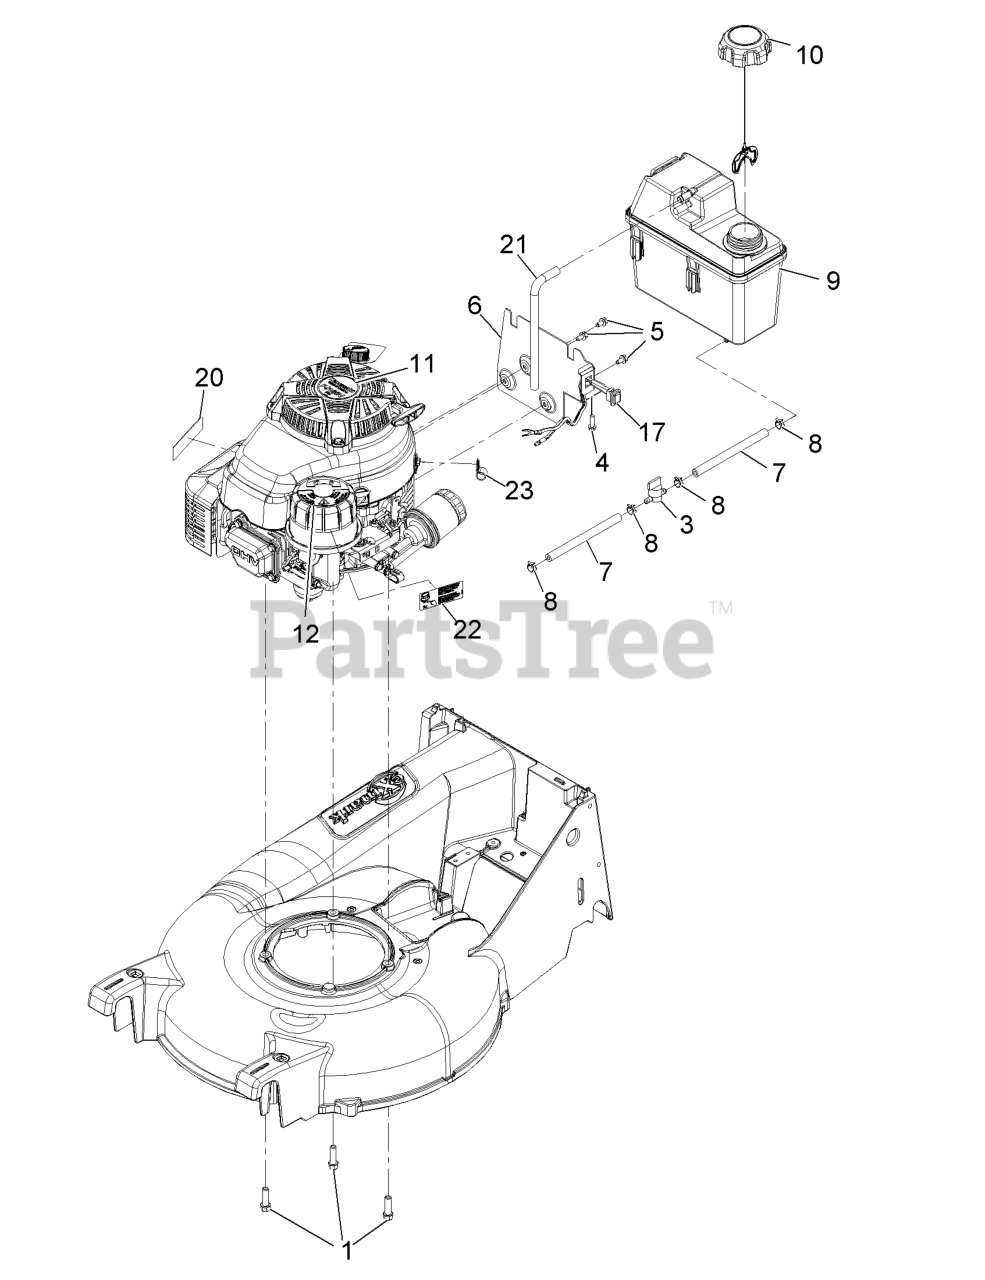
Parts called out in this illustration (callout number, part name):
1	SCREW-TAPTITE
3	VALVE-FUEL
4	SCREW-HWH
5	SCREW-HWH
6	BRACKET,FUEL TANK
7	HOSE-FUEL
8	CLAMP-HOSE
9	TANK-FUEL
17	HARNESS,RUN/STOP
20	DECAL-ARRESTER, SPARK
21	HOSE-VENT, CANISTER
22	DECAL, PRIMER
23	CLIP-LOOM
